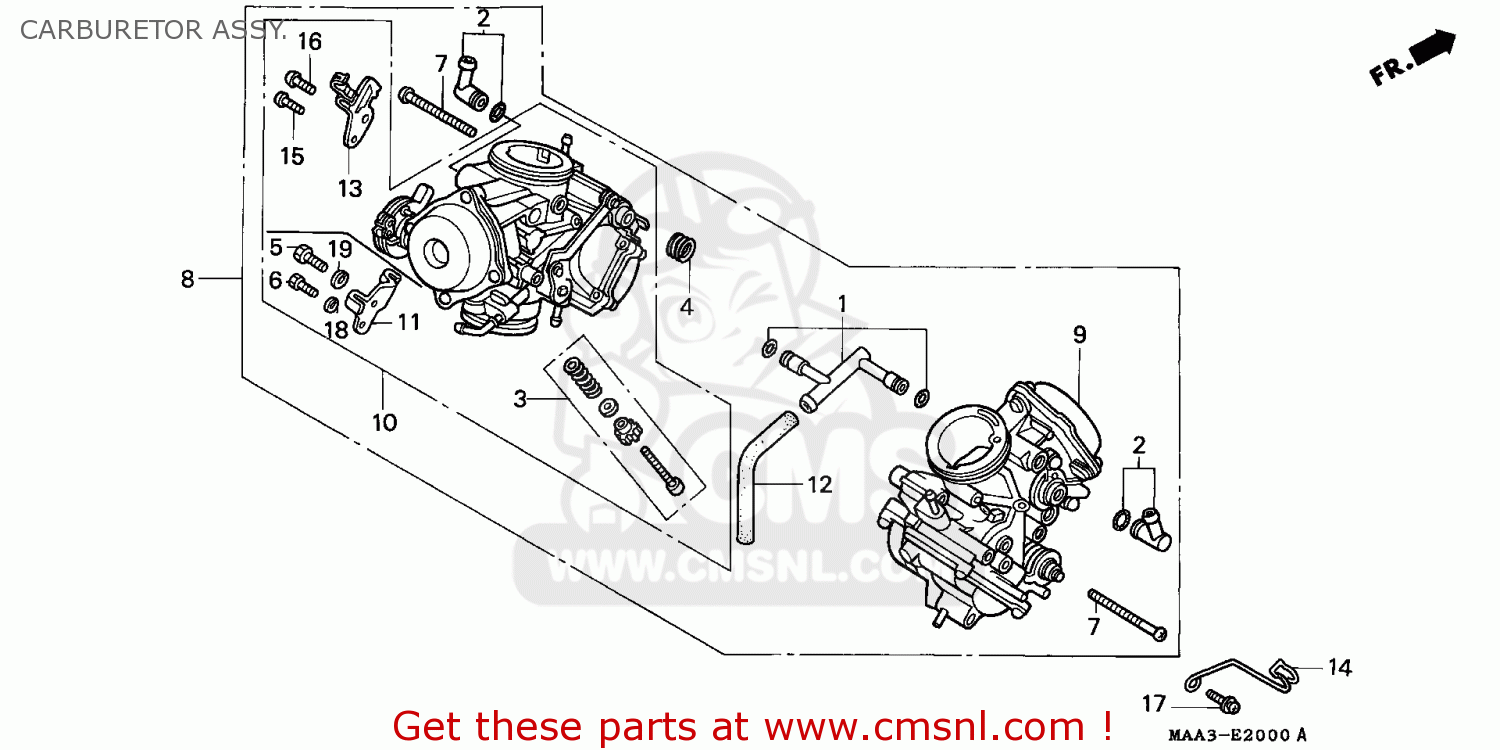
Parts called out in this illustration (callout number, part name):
1	JOINT SET
3	SCREW SET
4	SPRING
5	SCREW,PAN
7	WASHER,SCREW
8	CARBURETOR ASSY
9	CARBURETOR ASSY,F
10	CARBURETOR ASSY,R
12	TUBE
13	STAY COMP.,WIRE
14	CLAMP,H/T CODE
15	SCREW-WASHER 4X8
16	SCREW-WASHER,5X12
17	SCREW-WASH.,5X10
